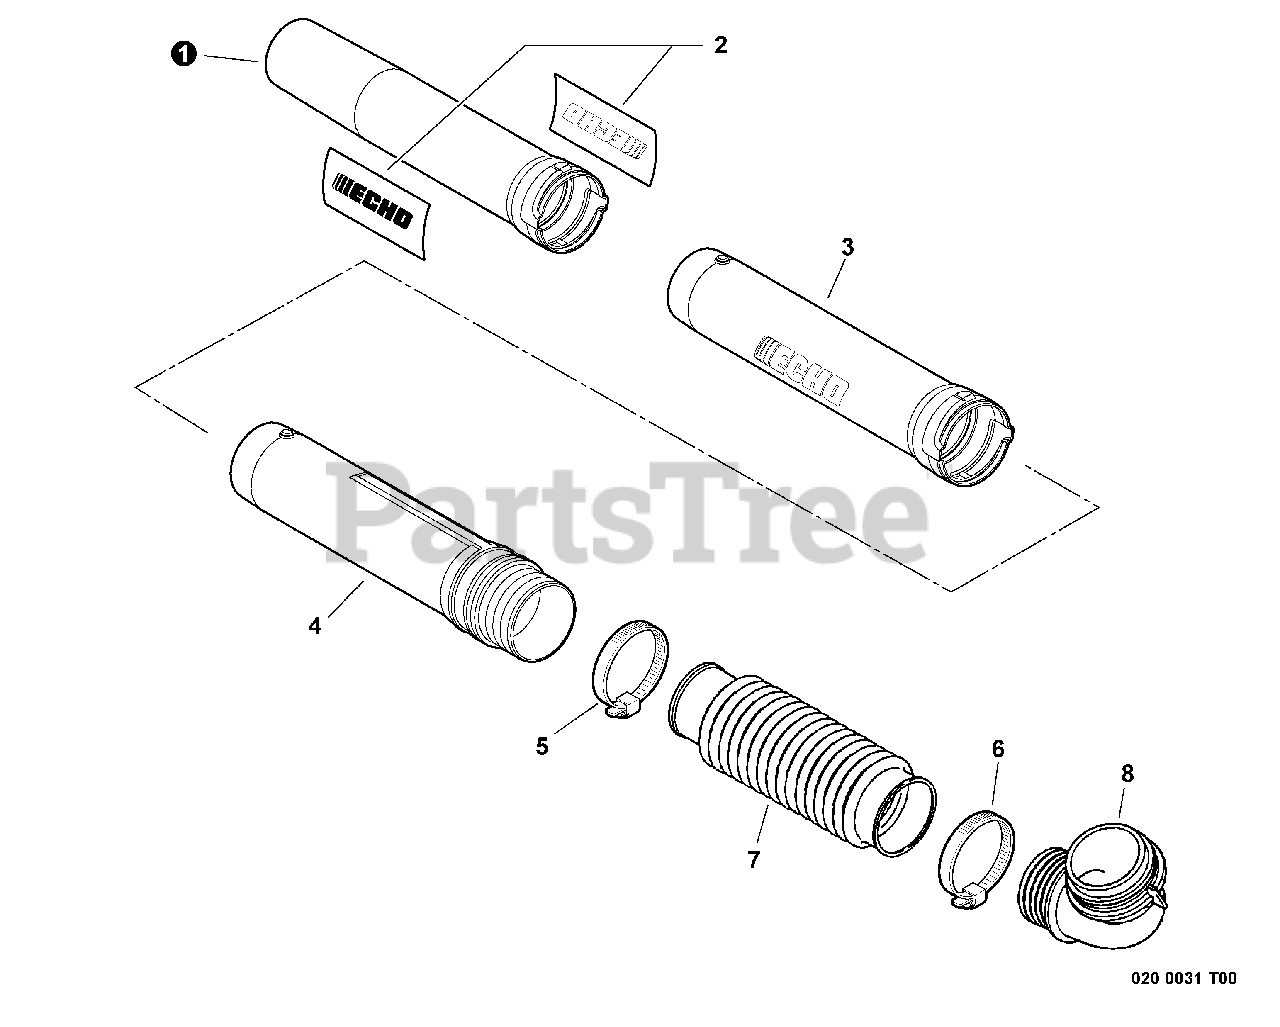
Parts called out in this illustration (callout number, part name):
1	TUBE, BLOWER - NOZZLE
2	LABEL, ECHO BLOWER TUBE
3	TUBE, BLOWER - STRAIGHT
4	TUBE, BLOWER - SWIVEL
5	CLAMP 58.7 MM / 82.5 MM
6	CLAMP - BAND
7	TUBE, FLEXIBLE
8	TUBE, BLOWER - ELBOW
